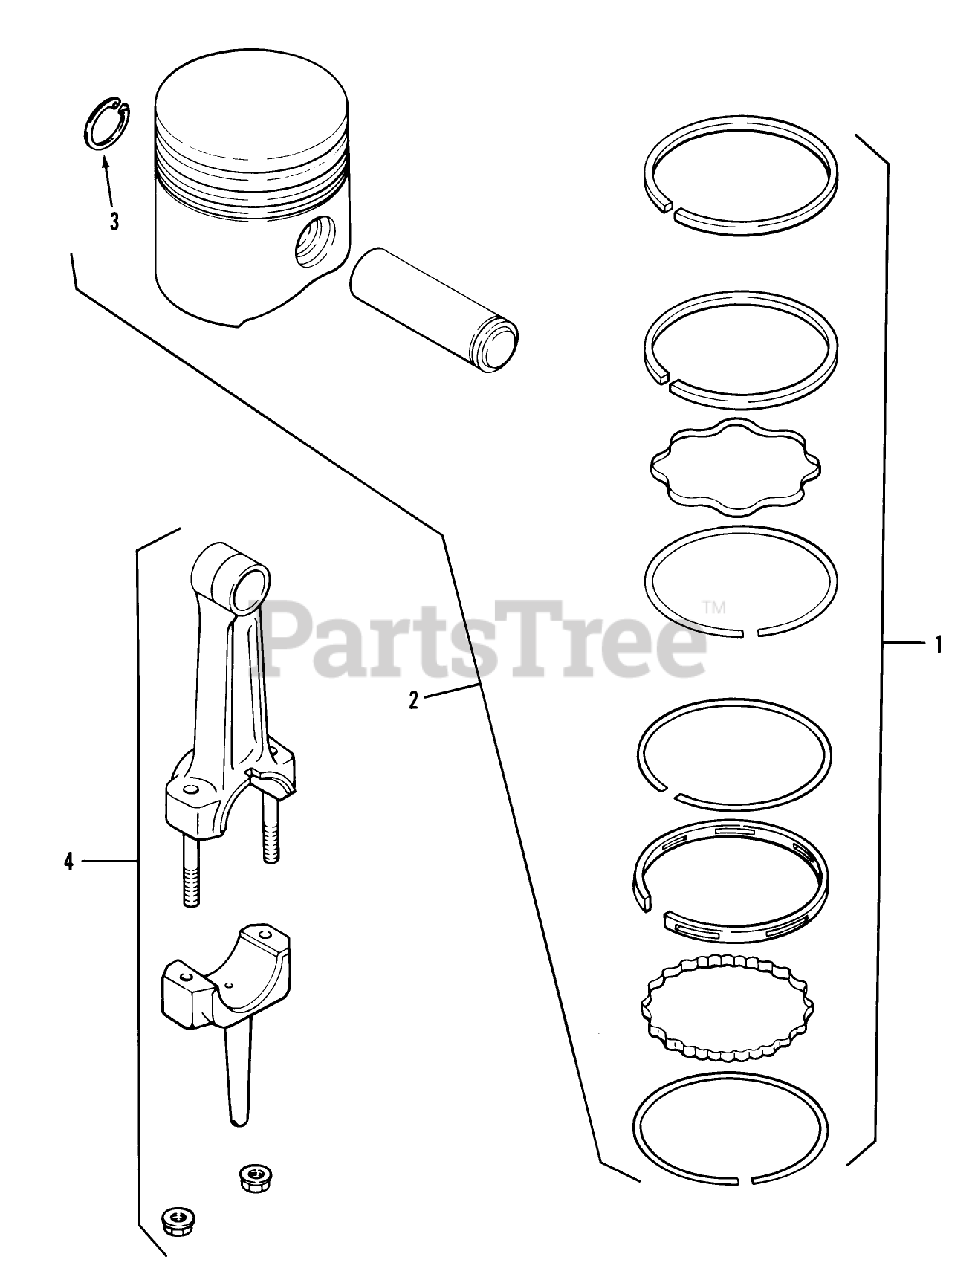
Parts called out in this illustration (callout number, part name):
1	KOHLER 232575
2	KOHLER 41-874-05
2	KOHLER 41-874-14
3	KOHLER 230004
4	KOHLER 41-067-10
